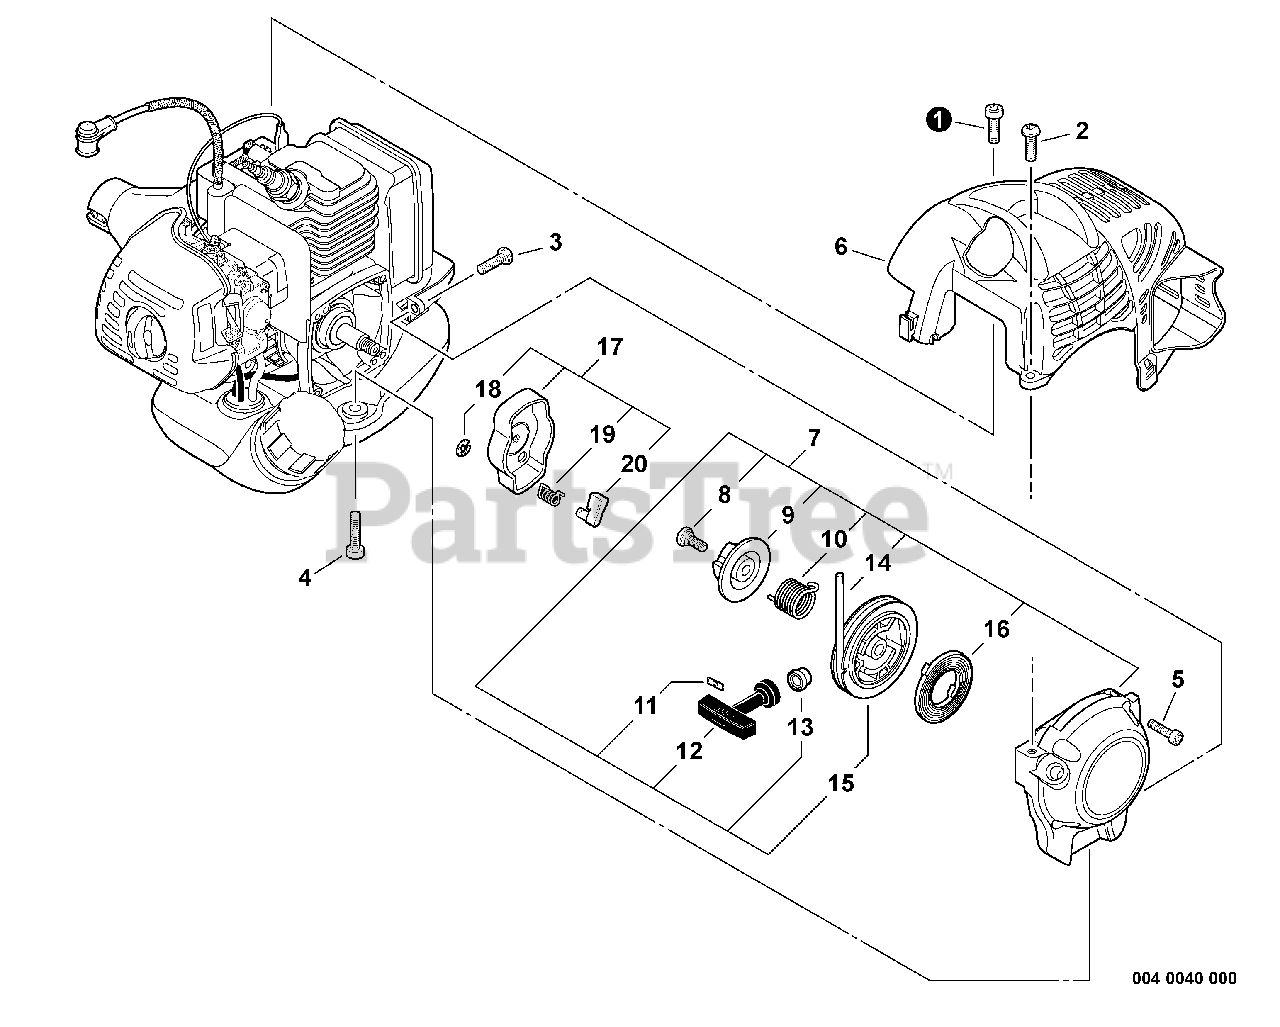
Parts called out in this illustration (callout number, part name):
1	SCREW - 5X16
2	SCREW - 5X16
3	SCREW - 5X16
4	SCREW - 5X20
5	SCREW - 4X16
6	COVER, ENGINE
7	STARTER ASSY
8	SCREW
9	PLATE, CAM
10	SPRING, DAMPER
11	RETAINER, ROPE
12	GRIP, STARTER
13	GUIDE, ROPE
14	ROPE, STARTER - 3X700
15	REEL, ROPE
16	SPRING, REWIND
17	STARTER PAWL ASSY
18	RING, RETAINING - 4
19	SPRING, RETURN
20	PAWL, STARTER
